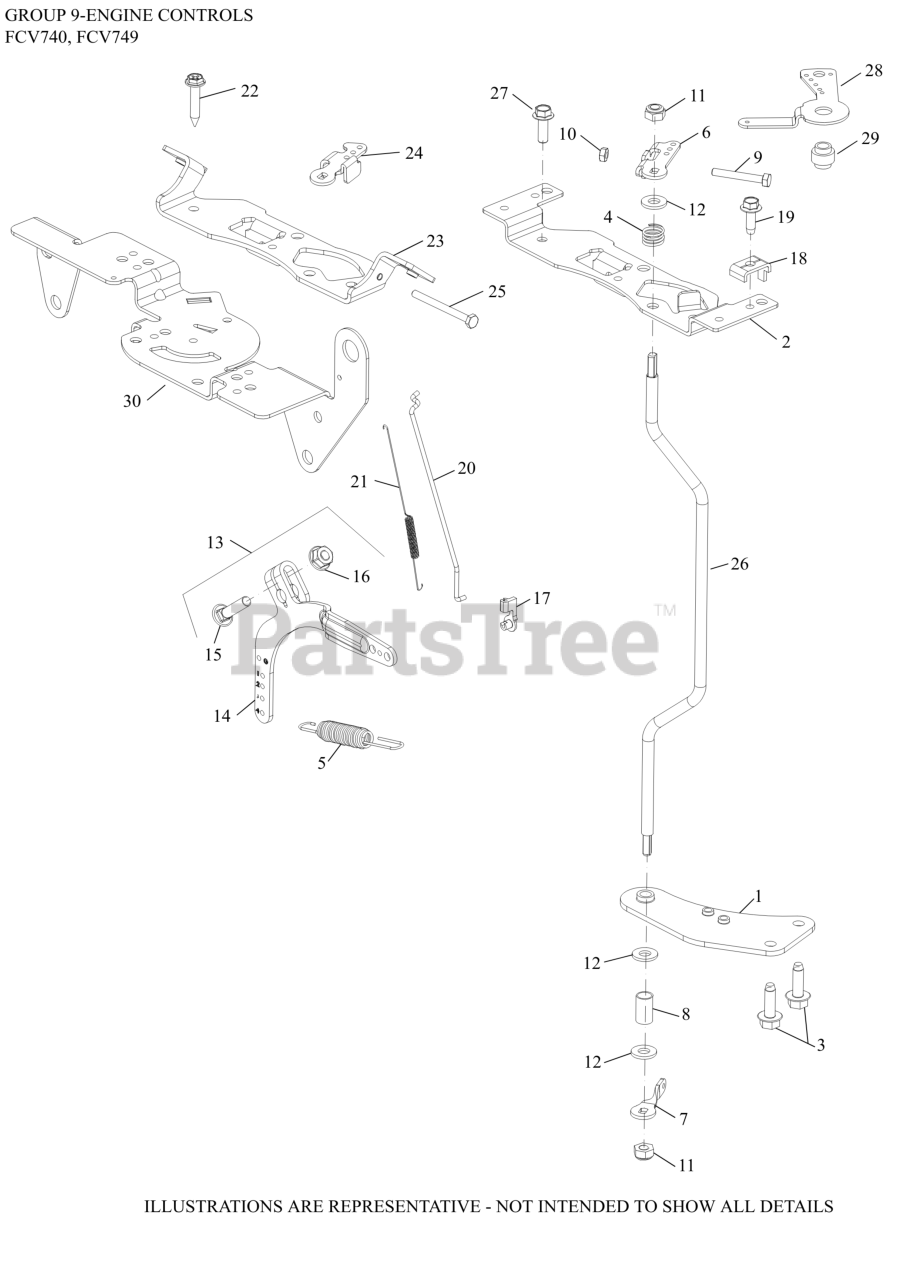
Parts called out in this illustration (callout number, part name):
1	BRACKET, THROTTLE SHAFT
2	BRACKET, CONTROL
3	SCREW, THREAD FORMING
4	SPRING, THROTTLE SHAFT
5	SPRING, GOVERNOR (BLUE)
6	LEVER, THROTTLE CONTROL
7	LEVER, THROTTLE CONTROL
9	SCREW, CAP M4X.7X30
10	NUT, M4X0.7
11	NUT, LOCK M6X1.0
12	WASHER, FLAT 1/4"
13	LEVER, GOVERNOR ASSEMBLY
14	LEVER, GOVERNOR - (#2409069S)
15	BOLT, RD HD SQ NECK M6X1.0X25
16	NUT, FLG M6X1.0
17	BUSHING, THROTTLE LINKAGE
18	CLAMP, CABLE-(#2523753S)
19	SCREW, THREAD FORMING
19	SCREW, MATHREAD M5 X 0.8 X 16
20	LINKAGE, THROTTLE
21	SPRING, LINKAGE
26	THROTTLE CONTROL SHAFT
27	SCREW, HI-LOW
